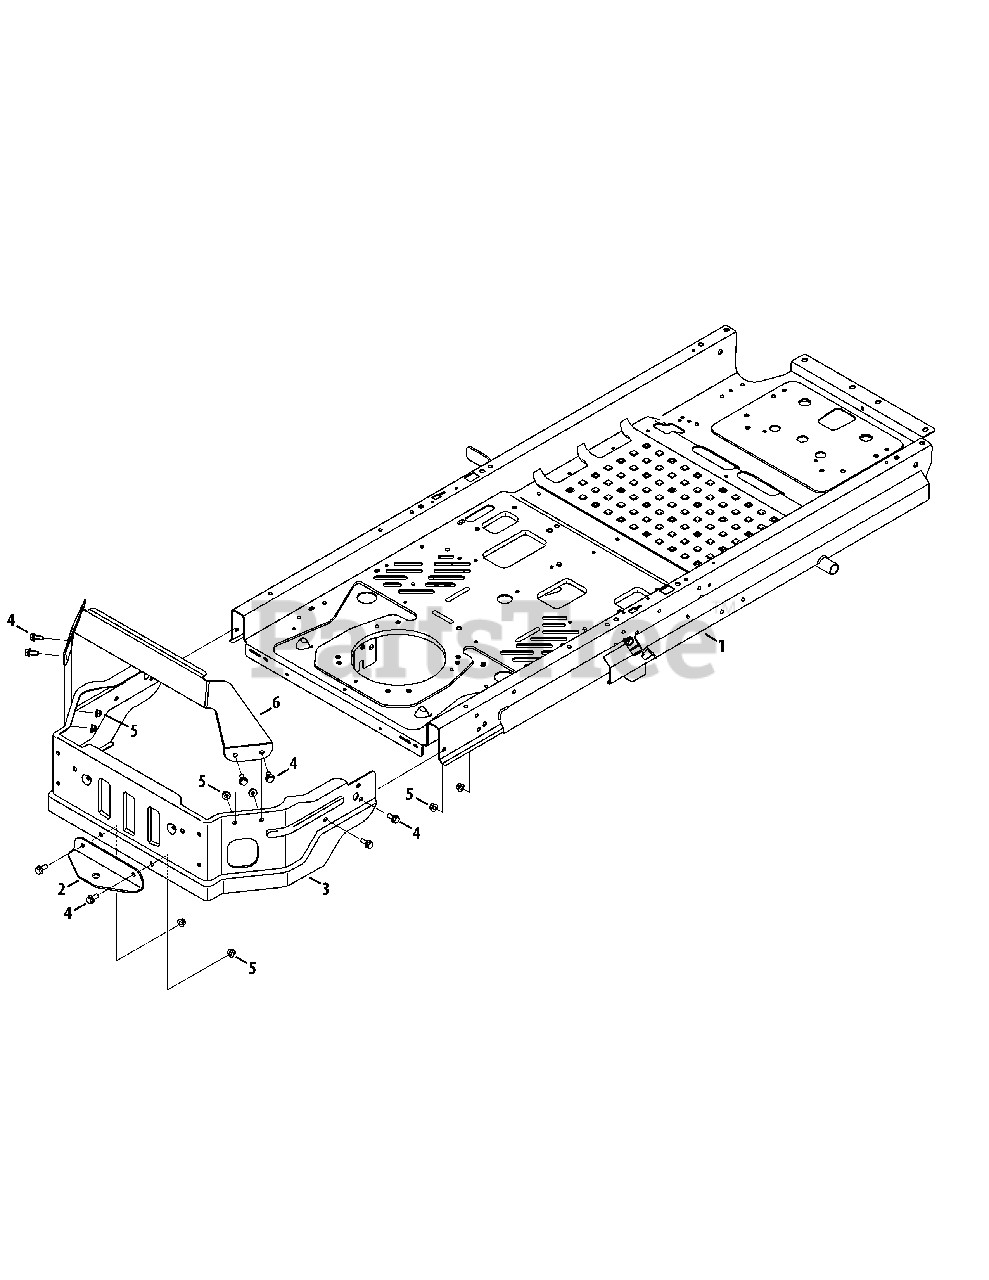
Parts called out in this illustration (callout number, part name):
1	Frame Assembly
4	Screw, 5/16-18, Hexflange
5	Flange Lock Nut, 5/16-18
6	Upper Bumper Bracket
